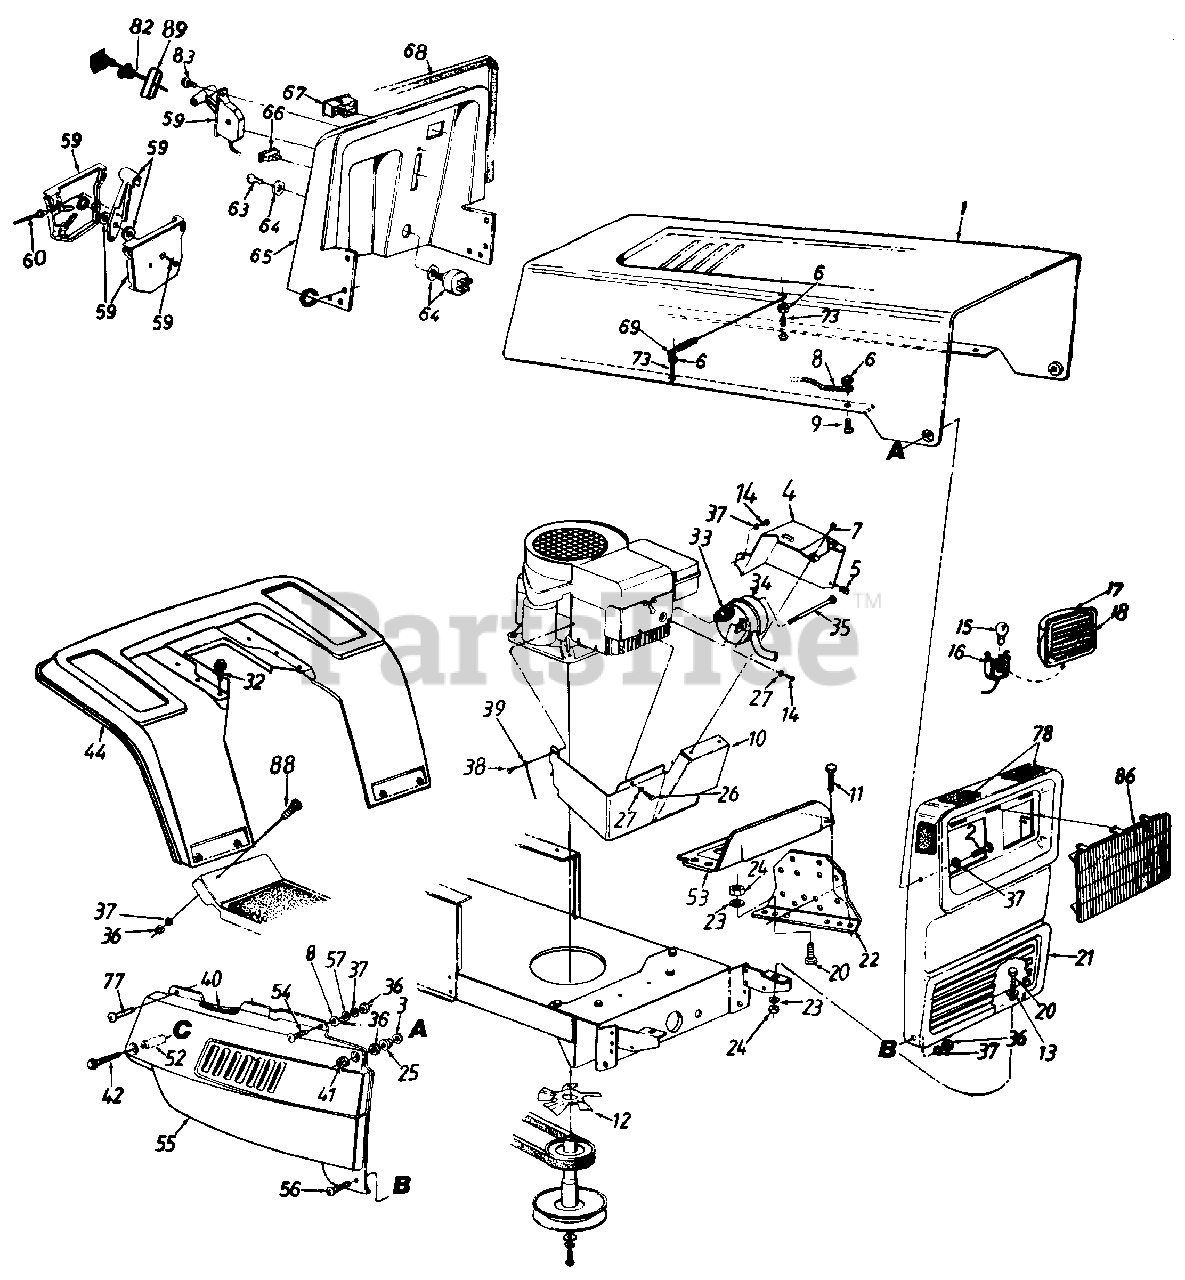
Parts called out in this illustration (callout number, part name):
1	Hood
2	Hex Bolt 1/4-20 x .88" Lg.
4	Muffler Heat Shield - L.H.
5	Speed Nut #10-24 Thd.
6	Hex Sems Nut #10-24 Thd.
7	Hex B-Tap. Scr. #10 x .38" Lg.
8	Hood Stop
9	Truss Hd. Scr. #10-24 x 1/2"
10	Muffler Heat Shield - Front
11	Hex Wash. Hd. B-Tap Scr. 5/16-18 x .5" Lg.
13	Fl-Wash. .344" I.D. x 1" O.D.
14	Hex Tap Scr. 1/4-20 x .5" Lg.
15	Bulb
16	Twist Lock - Bulb Socket
17	Headlight Housing
18	Lens
20	Hex Bolt 5/16-18 x .75" Lg.
24	Hex Nut 5/16-18 Thd.
25	Shld. Spacer
26	Hex Bolt 1/4-20 x 3/8" Lg.
27	Spr. Wash. 1/4" I.D.
33	Exhaust Gasket
34	Muffler (B&S)
35	Shoulder Bolt
36	Hex Nut 1/4-20 Thd.
37	L-Wash. 1/4" I.D.
38	Truss Mach. Scr. 5/16-18 x .75" Lg.
39	Ground Wire 7.5"
40	Trim Strip - 12"
41	Acorn Nut 1/4-20 Thd.
42	Hex TT-Tap Scr. 1/4-20 x 1.75" Lg.
57	Fl-Wash. .281" I.D. x .73" O.D.
59	Throttle Control Box Ass'y.
60	Throttle Control Wire (B&S)
63	Ignition Key
64	Ignition Switch
67	Ammeter
68	Trim Strip - 31"
69	Hood Spring
73	Hex Scr. #10-24 x 1.0" Lg.
77	Hex Wash. Hd. Tap Scr. 1/4 x .75" Lg.
78	Foam Strip 3/8 x 1-1/8" x 1-1/2 Lg.
82	Choke Control 29" Lg.
83	Truss Mach. AB-Tap Scr. #10 x .5" Lg.
86	Headlight Bezel
88	Truss Mach. Scr. 1/4-20 x .5" Lg.
89	Retainer Clip
17308A-0640	PANEL-SIDE RH - CO-OP GREEN (0640)
17308A-0691	PANEL-SIDE RH - BLACK JACK (0691)
17309A-0638	PANEL-SIDE-LH - MTD/TROY-BILT RED (0638)
17458A-0665	PANEL-SIDE RH - YARDMAN GREEN (0665)
17459A-0638	PANEL-SIDE-LH - MTD/TROY-BILT RED (0638)
